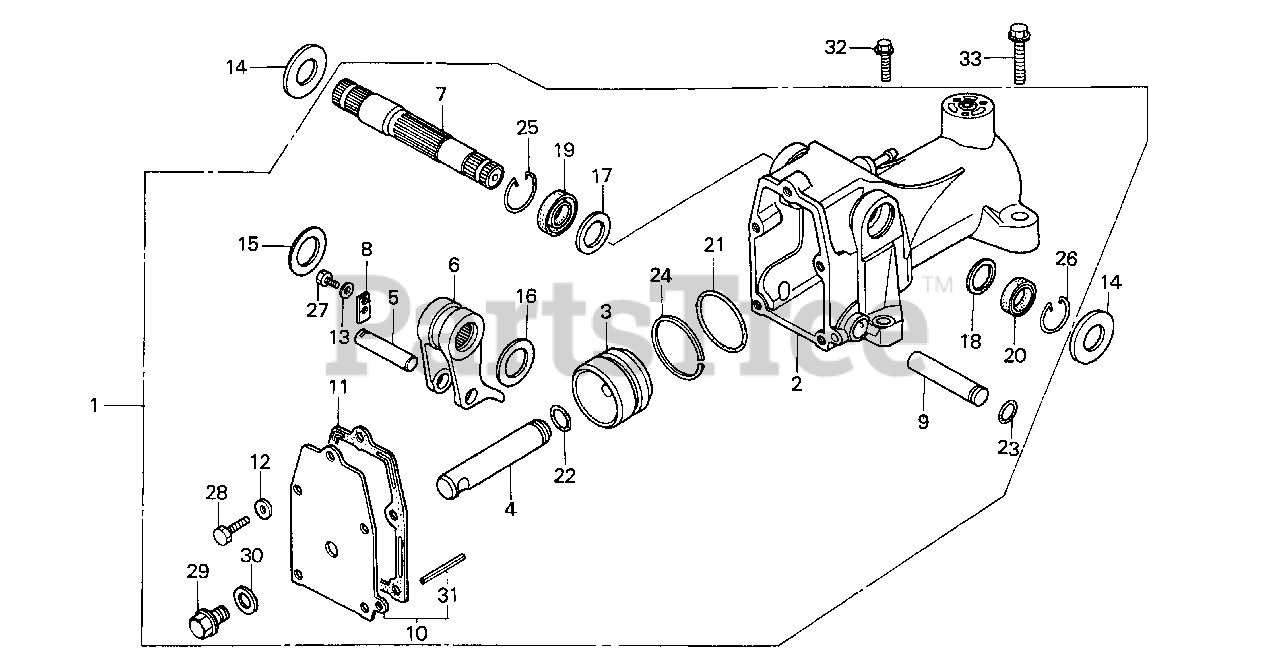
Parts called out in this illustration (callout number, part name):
1	CYLINDER ASSY., HYDRAULIC
2	CYLINDER, HYDRAULIC
3	PISTON, HYDRAULIC (60MM)
4	ROD, CONNECTING
5	PIN, CONNECTING ROD
6	ARM, HYDRAULIC CYLINDER
7	SHAFT, HYDRAULIC CYLINDER
8	PLATE, CONNECTING ROD PIN
9	SHAFT, STOPPER
10	COVER, CYLINDER
11	GASKET, HYDRAULIC CYLINDER COVER
12	WASHER (8MM)
13	WASHER, CONICAL SPRING (6MM)
14	WASHER, THRUST (25.5X50X5)
15	WASHER, PLAIN (INNER) (28.5MM)
16	WASHER, PLAIN (INNER) (25.5MM)
17	WASHER, PLAIN (OUTER) (30.5MM)
18	WASHER, PLAIN (OUTER) (25.5MM)
19	OIL SEAL (30X44X8)
20	OIL SEAL (25X38X9)
21	O-RING, HYDRAULIC CYLINDER
22	O-RING (17X3.5)
23	O-RING (13.8X2.4)
24	RING, BACK-UP
25	RING, STOPPER (49)
26	RING, STOPPER (43)
27	BOLT, HEX. (6X12)
28	BOLT, HEX. (8X22)
29	BOLT, DRAIN PLUG (14MM)
30	WASHER, DRAIN PLUG (14MM)
31	PIN, SPRING (6X40)
32	BOLT, FLANGE (10X55)
33	BOLT, FLANGE (12X58)
33	BOLT, FLANGE (12X50)
